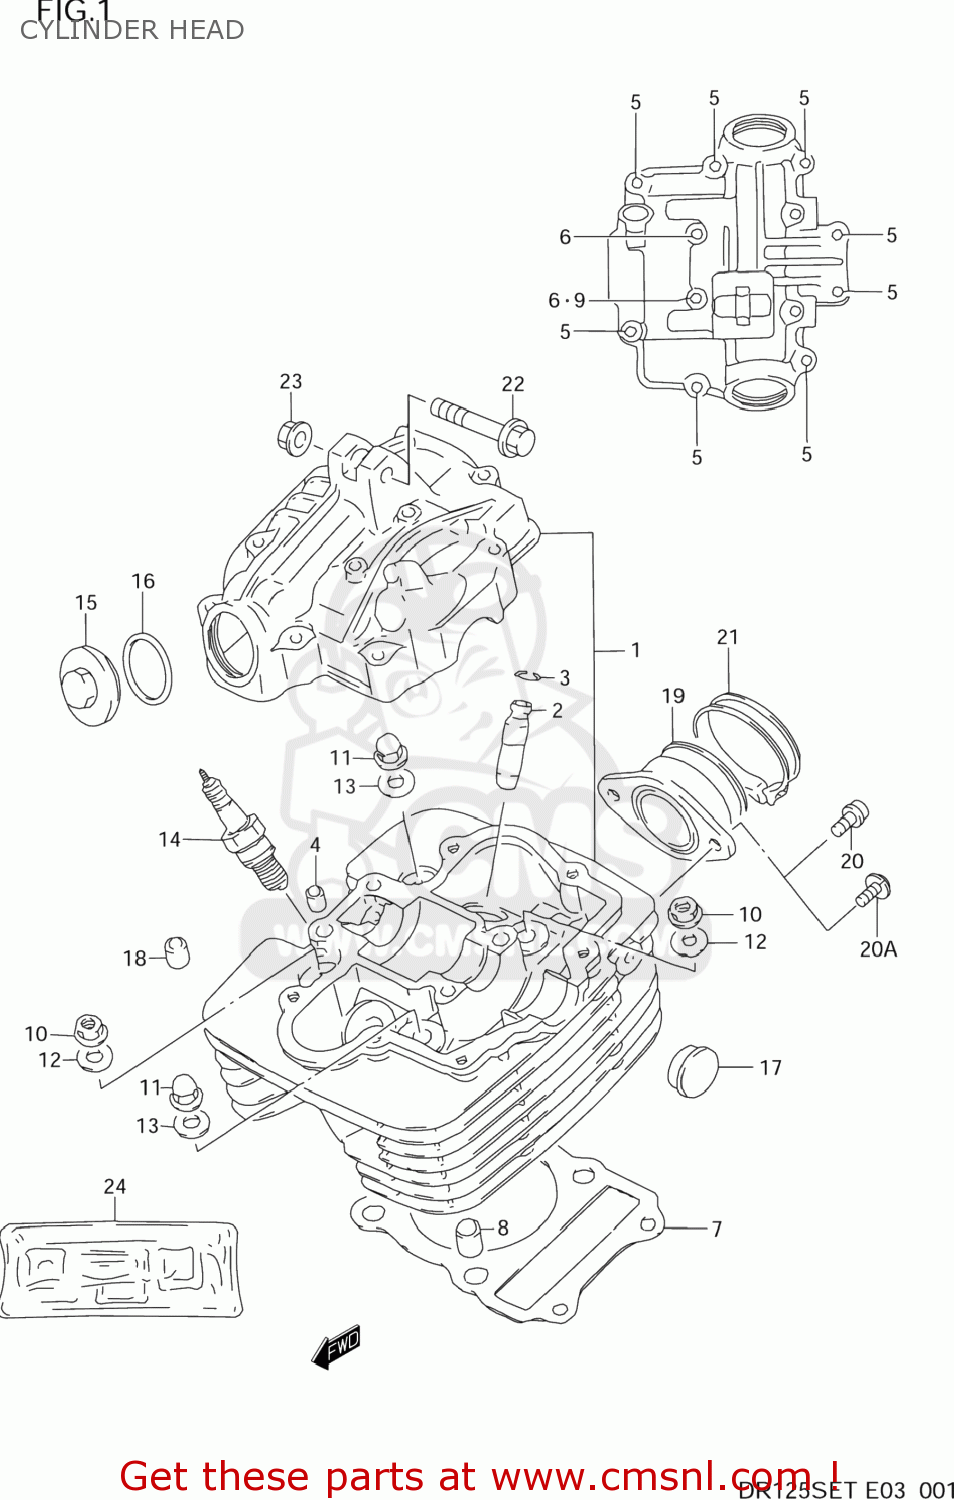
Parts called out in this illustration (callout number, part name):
1	HEAD ASSY,CYLINDER
2	GUIDE,VALVE
3	RING,SNAP
4	PIN(6.2X8X11)
5	BOLT
6	BOLT
7	GASKET,CYLINDER HEAD (NAS)
8	PIN
9	GASKET(5.8X13X1.2) (NAS)
10	NUT
11	NUT
12	WASHER(8.5X19X2.3)
13	GASKET(8.5X17X2.3) (NAS)
14	PLUG,SPARK(DR8EA)
15	CAP,INSPECTION
16	O RING(D:3,ID:29.5)
17	PLUG(OD:22.5)
18	PAD,CYLINDER HEAD
19	PIPE,INTAKE
20	BOLT MAGNETO S
20A	SCREW
21	CLAMP
22	BOLT 8X50
23	NUT
24	GASKET SET (NAS)
